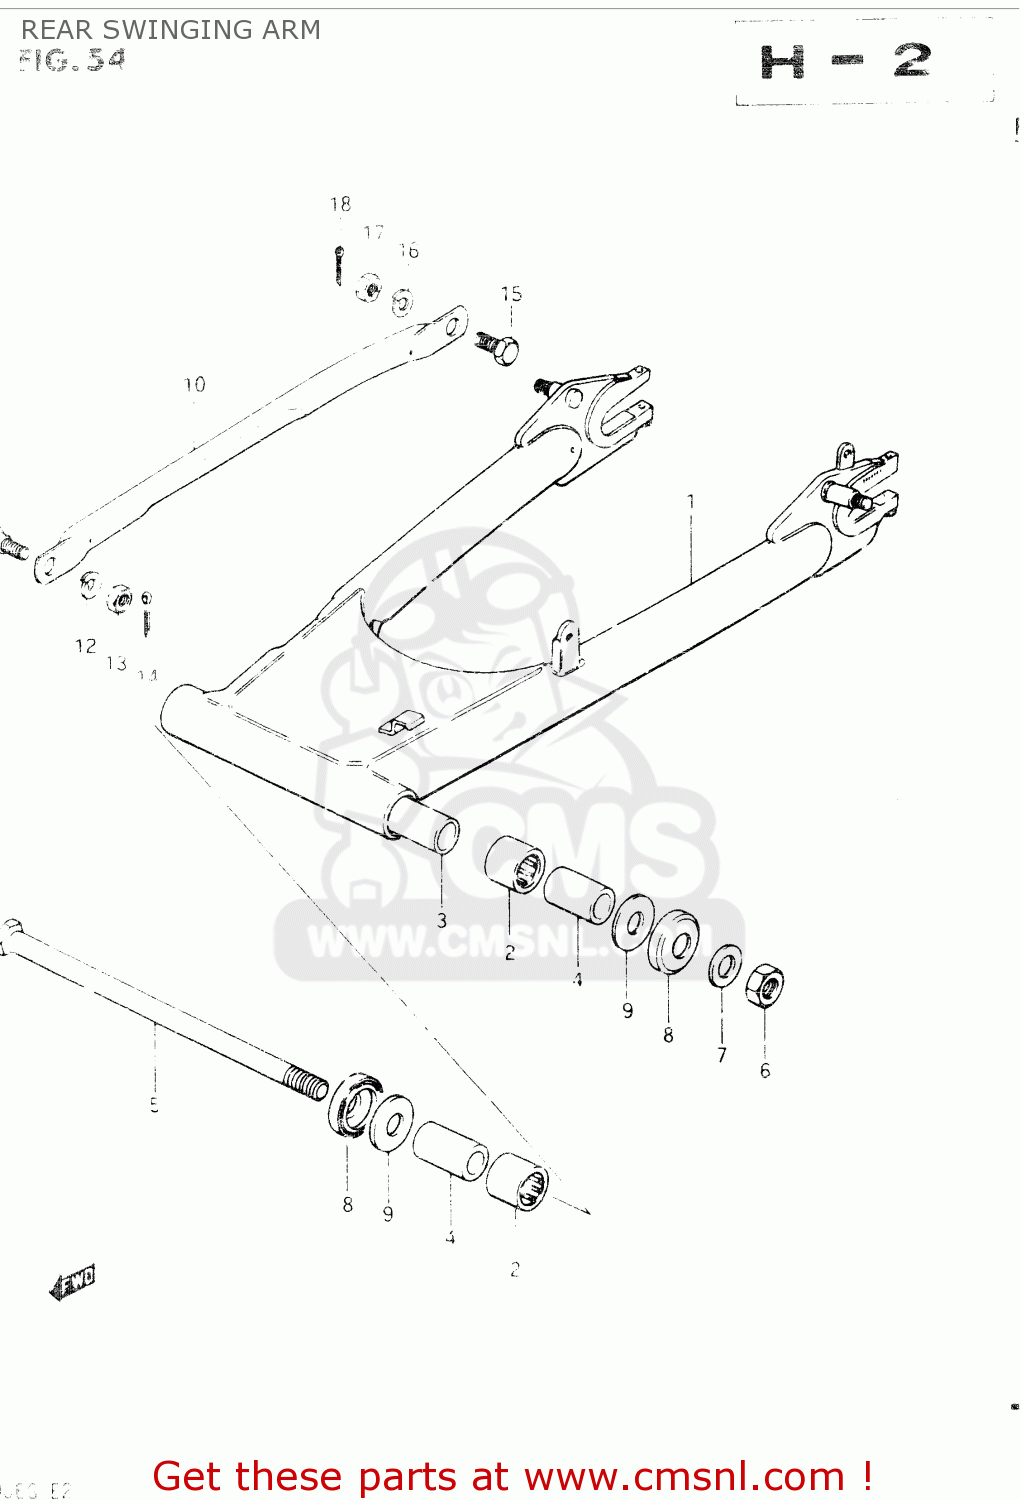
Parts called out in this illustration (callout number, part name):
1	ARM,REAR SWING
2	BEARING(22X29X30)
3	SPACER,SWINGINGARM CTR
4	SPACER,RR SWGARM PIVOT
5	SHAFT,REAR SWING ARM
6	NUT 14MM
7	WASHER
8	CVR,RR SWGARM DUST SEAL(OD:40)
9	WASHER(14.2X34X1)
10	LINK,REAR TORQUE
11	BOLT(10X24.5)
12	LOCK WASHER
13	NUT
14	PIN 20X20
15	BOLT(10X31)
16	LOCK WASHER
17	NUT
18	PIN 20X20
